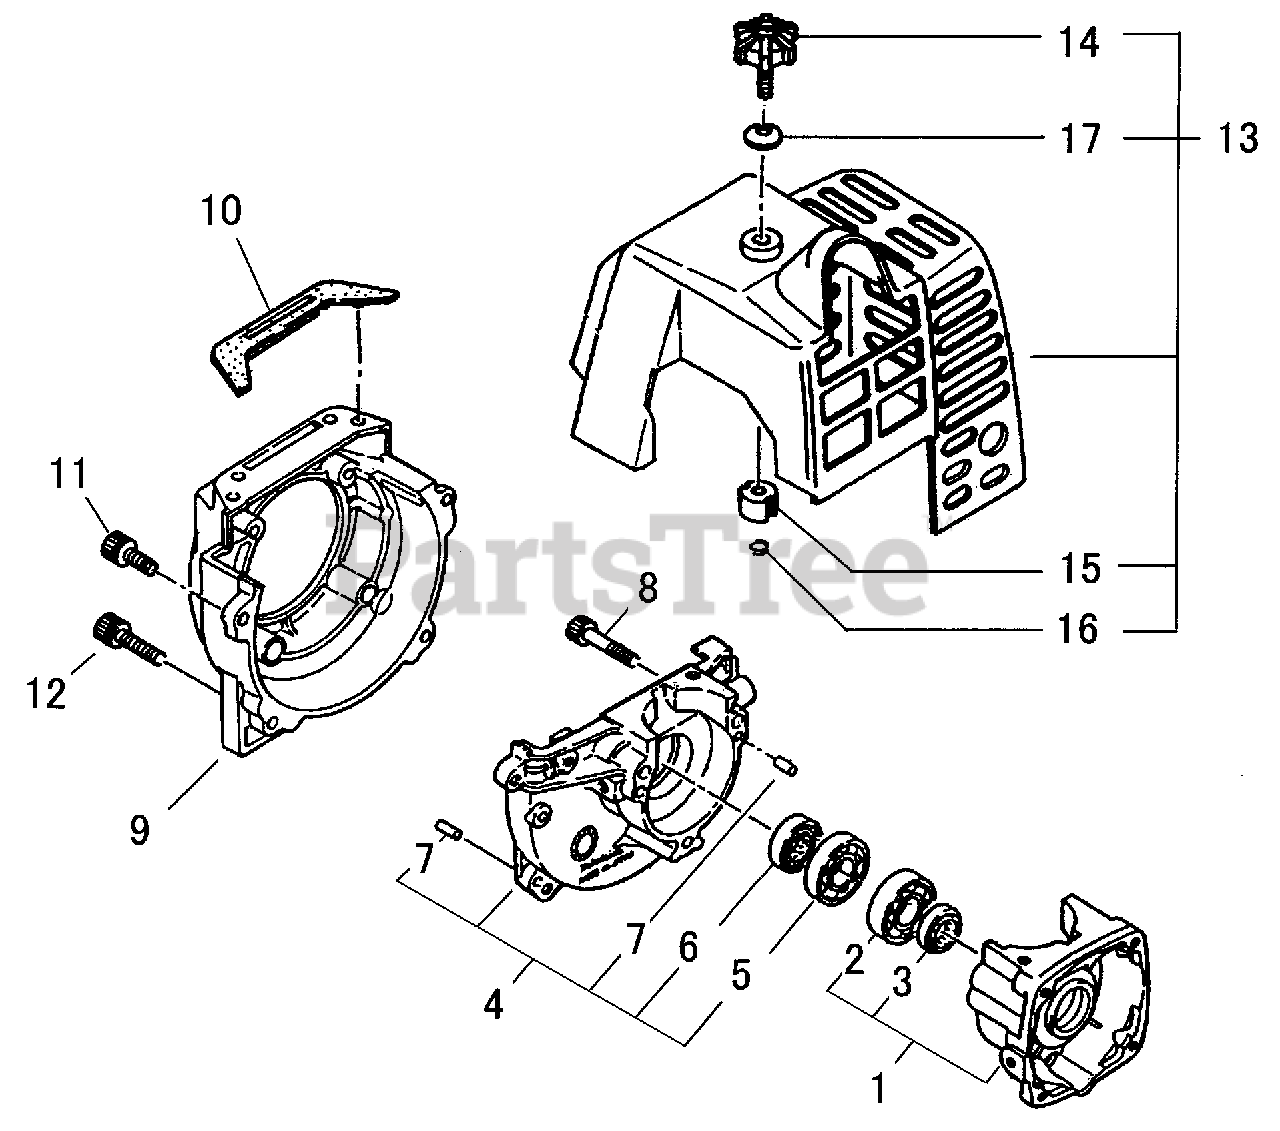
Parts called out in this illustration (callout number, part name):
1	CRANKCASE ASSY - REAR
2	BEARING, BALL 6001 C3
3	SEAL, OIL - 12
4	CRANKCASE ASSY - FRONT
5	BEARING, BALL 6001 C3
6	SEAL, OIL - 12
7	PIN - LOCATING
8	SCREW - 5X25
9	COVER, FAN
10	CUSHION
11	SCREW - 5X16
12	SCREW - 5X35
13	ENGINE COVER KIT
14	THUMBSCREW
15	INSULATOR
16	CLIP
17	WASHER - CONICAL
